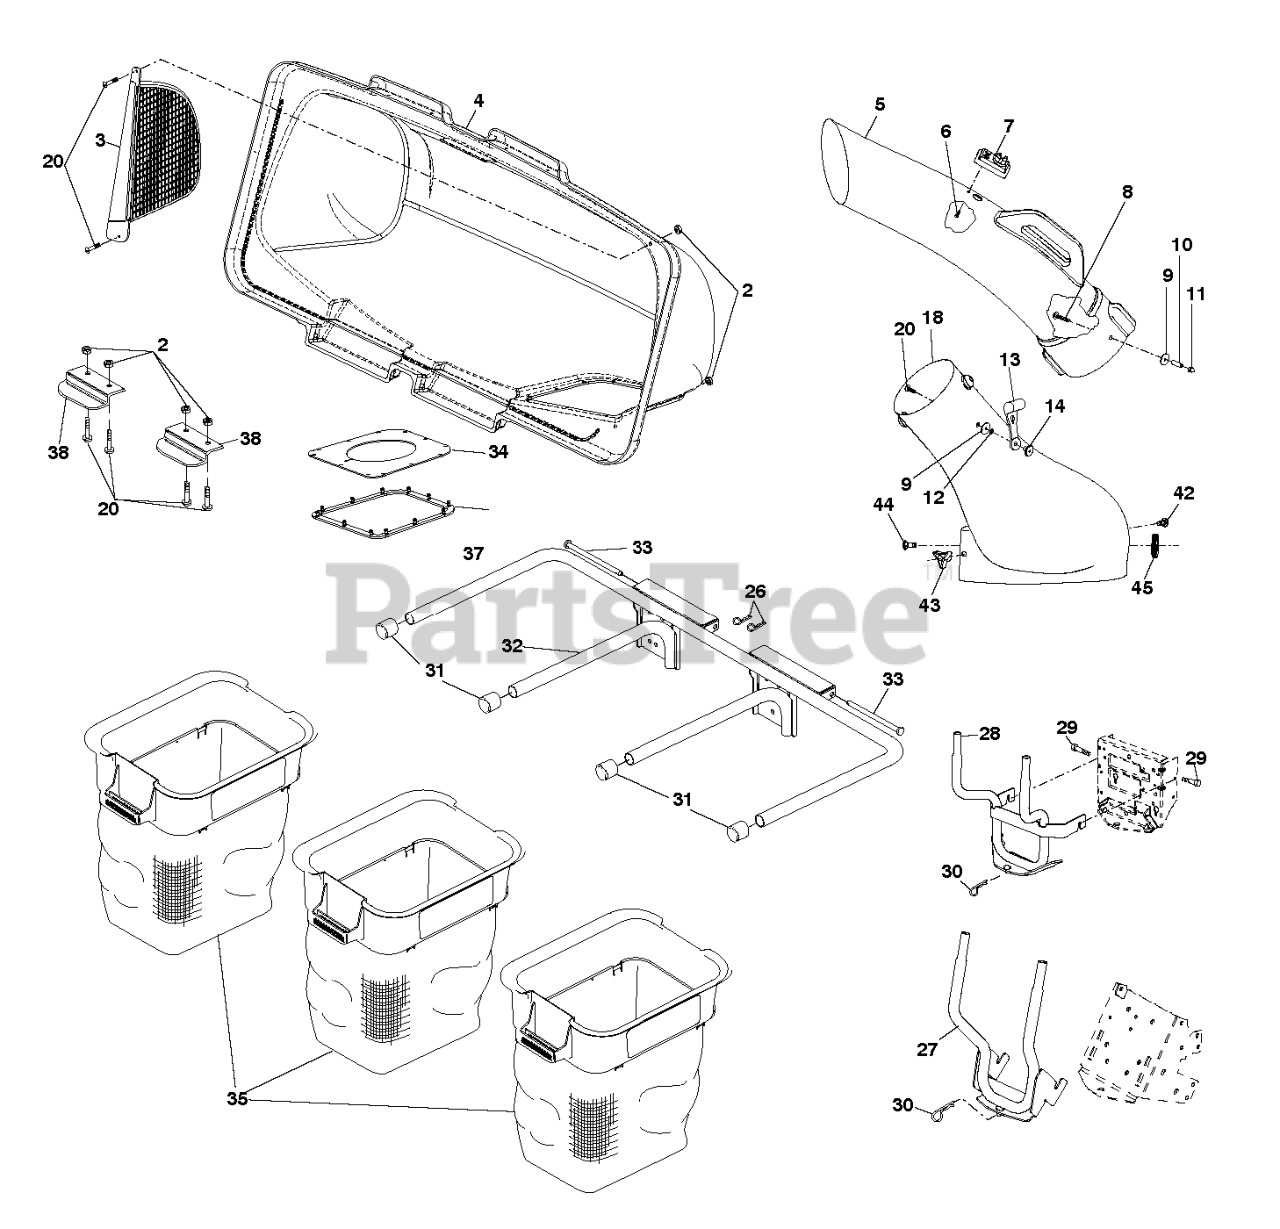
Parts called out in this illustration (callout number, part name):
3	SCREEN.COVER.BAGGER
4	COVER.ASM.3BIN.GENERIC.
5	CHUTE.54".CLEARCT.TR.UPR.MS428
7	INDICATOR ASM BAG
8	SCREW
9	RP STEEL WASHER
11	NUT
12	LOCKWASHER #10
13	LATCH.HOOD.
14	WELDNUT
18	CHUTE.54F.LOWER.MS428
20	SCREW
26	RETAINER SPRING
27	BAGGER.ASM.SUPPORT.GT.TEX.BLAC
28	BAGGER.ASM.PNT.3-BIN.
29	SHOULDER BOLT, SELF-TAP
30	SPRING.RETAINER.YELLOW.ZINC
31	PLUG, TUBING END
32	BAGGER.ASM.FRAME.3BIN.BLACK
33	BAGGER.HINGE.PIN
34	SEAL.BAGGER.TOP.3-BIN.BLK
35	CONTAINER BAG, SOFT
37	GASKET.COVER.BAGGER
38	LATCH CER38
42	BOLT D
43	KNOB.HANDLE.3/8.TRI-POINT.BLAC
45	NUT.KNOB.WINGNUT
